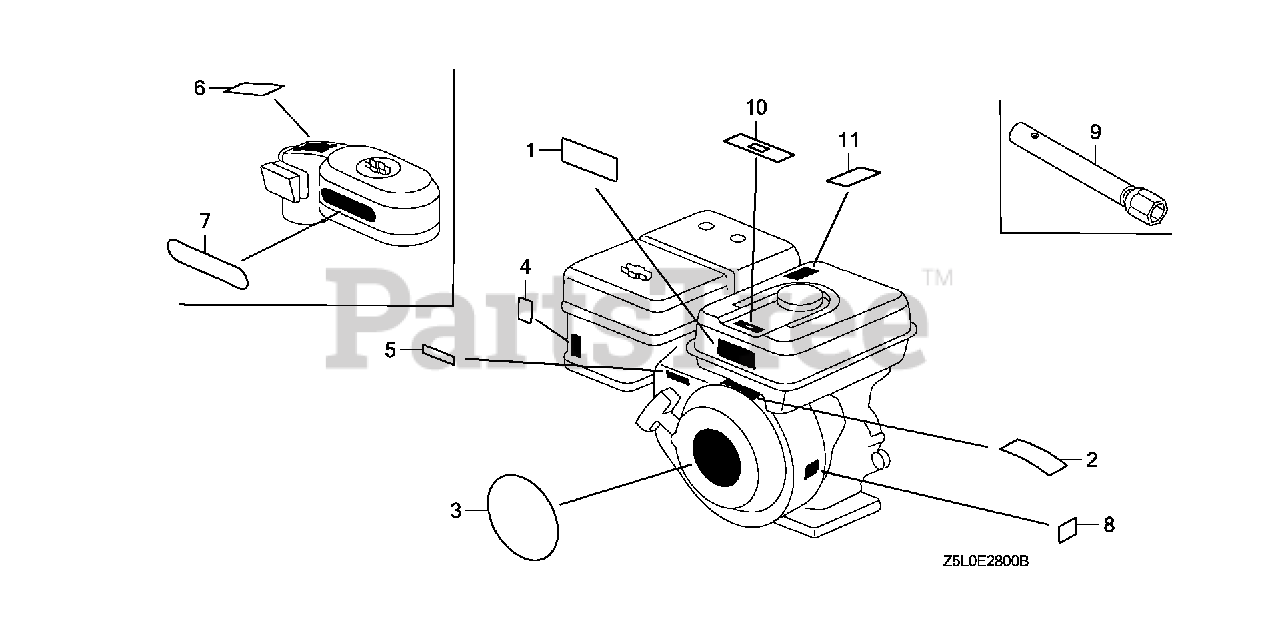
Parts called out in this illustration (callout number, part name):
1	MARK, OPERATOR CAUTION (ENGLISH)(MADE IN JAPAN)
1	MARK, OPERATOR CAUTION (PICTOGRAPH)(MADE IN JAPAN)
3	EMBLEM (11. (HONDA)
3	EMBLEM (GX340)
4	MARK, CHOKE (GRAY)
5	MARK, THROTTLE INDICATION
11	MARK, EX. CAUTION (ENGLISH)
